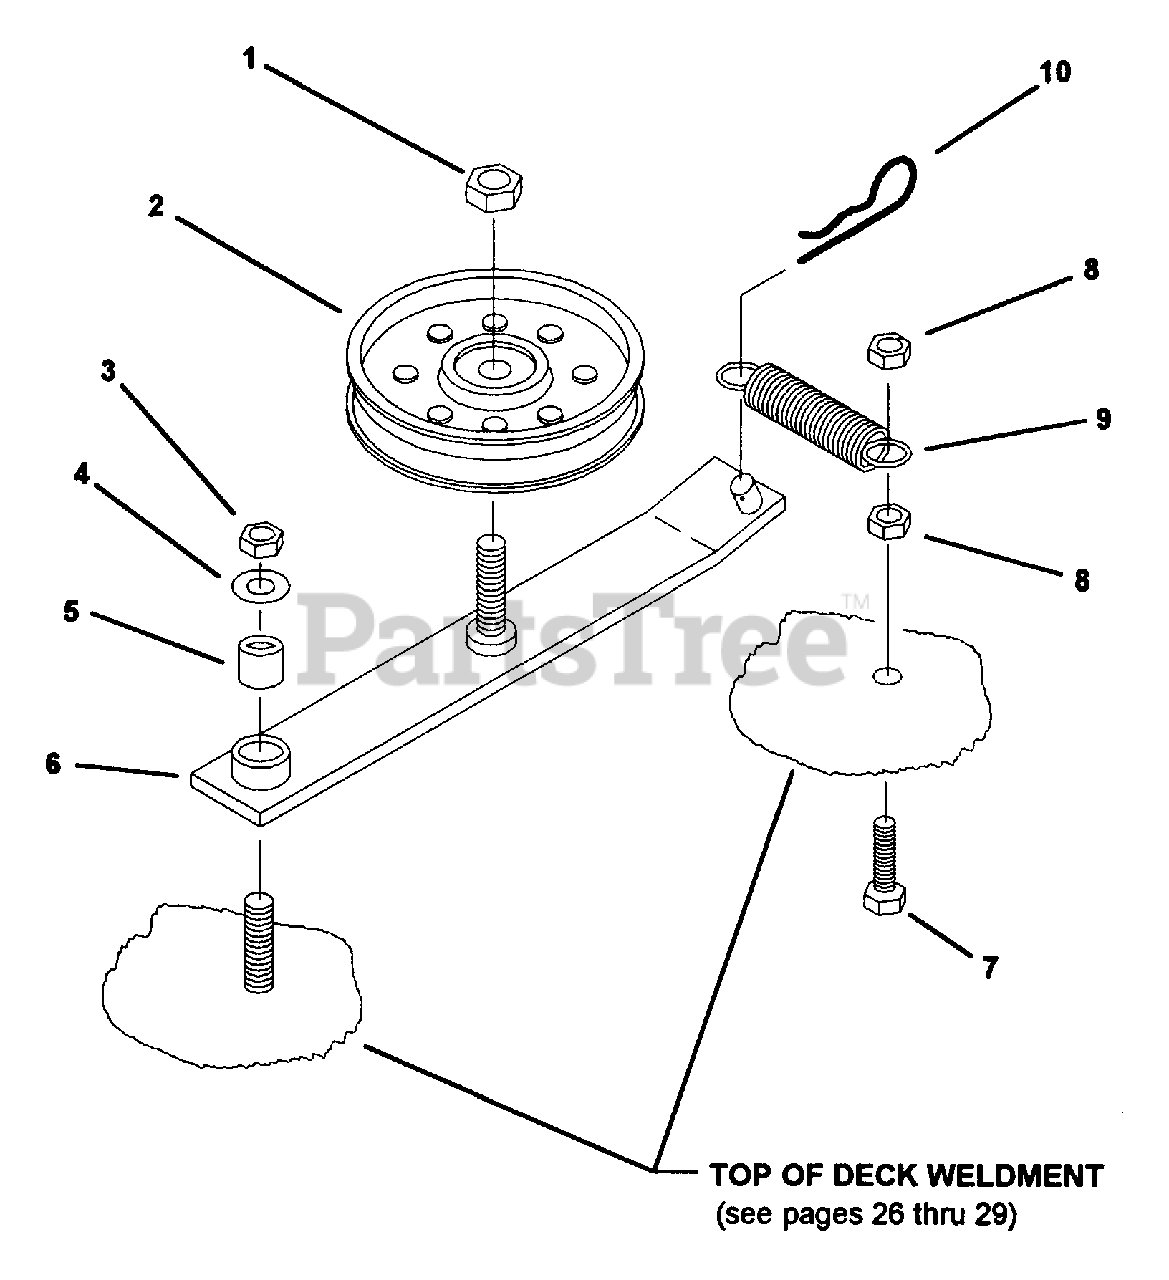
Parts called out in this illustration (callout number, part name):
1	NUT, HEX. 1/2-13 NYLOC
2	PULLEY, FLAT IDLER, 1/2 BORE, 4" O.D.
3	NUT, HEX. 3/8-16 NYLOC
4	WASHER, FLAT STD. 3/8" W SERIES
5	BEARING OILITE, 3/8 I.D. X 5/8" O.D.
6	SINGLE IDLER ARM WELDMENT, 60" DECK
6	SINGLE IDLER ARM WLDT 42" & 48" DECK
7	BOLT, 3/8-24 X 1-1/4" GR. 5
8	NUT, 3/8-24, M-F LOCKNUT
9	SPRING, EXTENSION, 3/4 X 4" O.A.L.
10	PIN, HAIR SPRING, 1/8 X 2-1/2"
